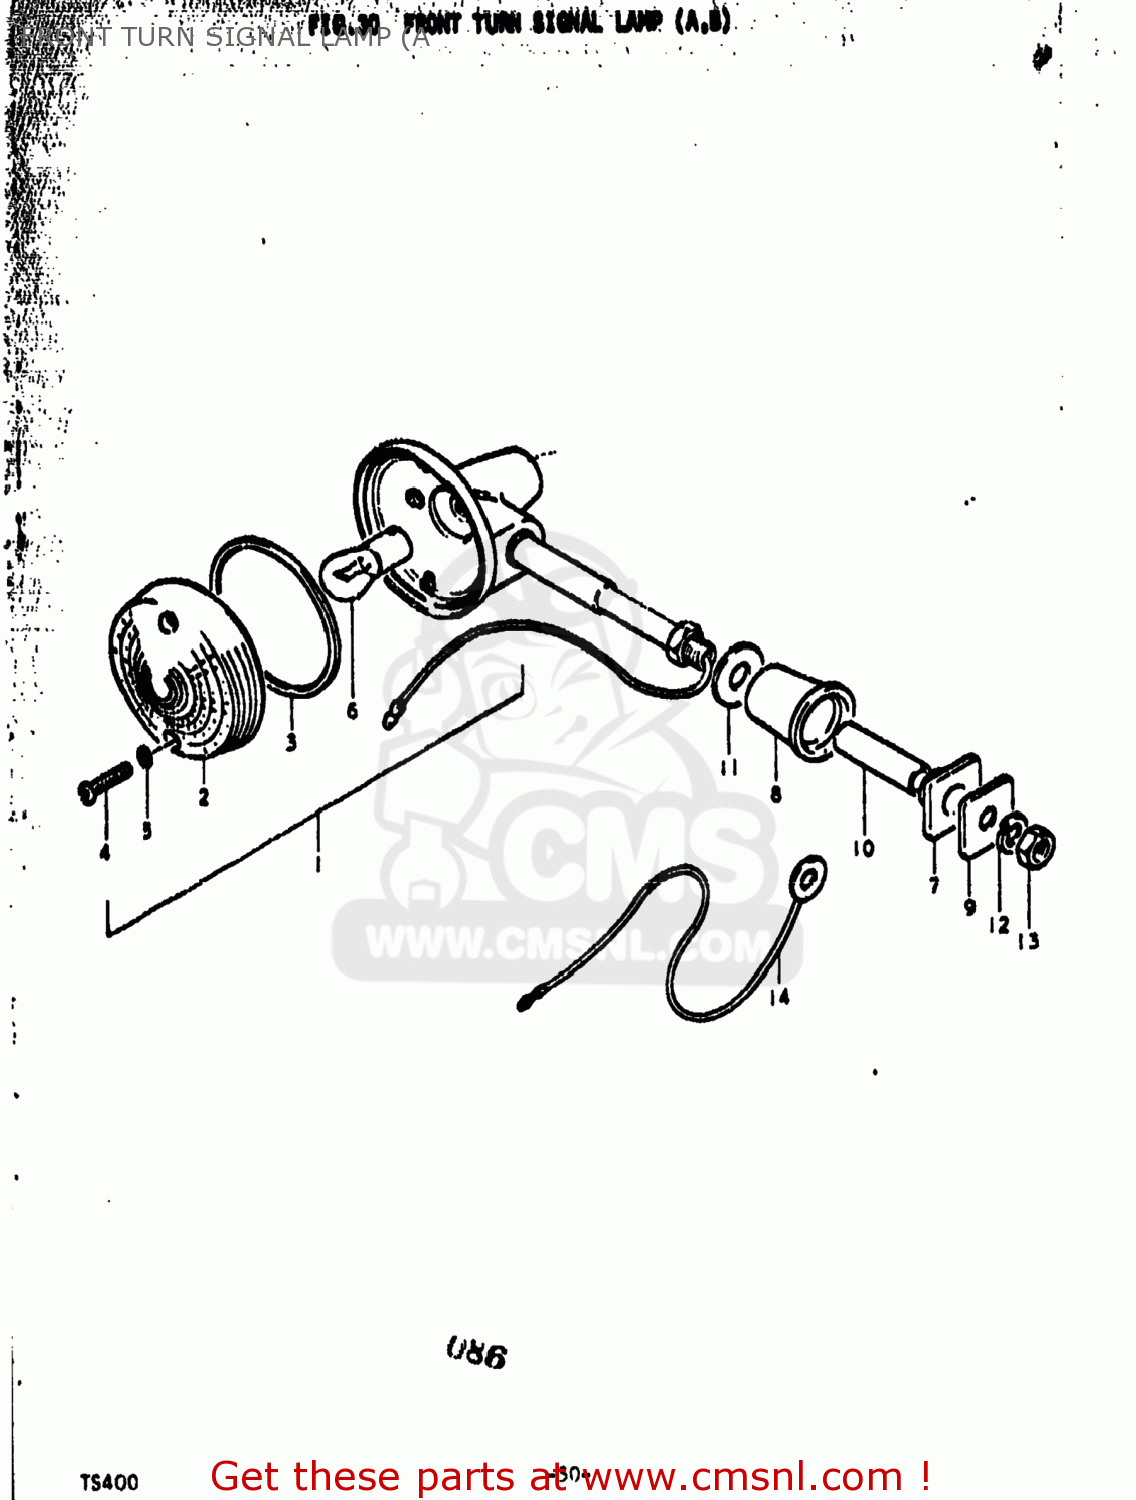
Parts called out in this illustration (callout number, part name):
1	LAMP ASSEMBLY,FRONT TURN SIGNAL
2	LENS
3	GASKET (NAS)
4	SCREW
5	GASKET (NAS)
6	BULB(6V17W,STANLEY,A4513A)
7	CUSHION,FRONT TURNSIGNAL
8	CUSHION
9	PLATE, TURN SIGNAL
10	SPACER, TURN SIGNAL
11	WASHER (10.5X30X2.3)
12	LOCK WASHER
13	NUT
14	LEAD WIRE,EARTH
